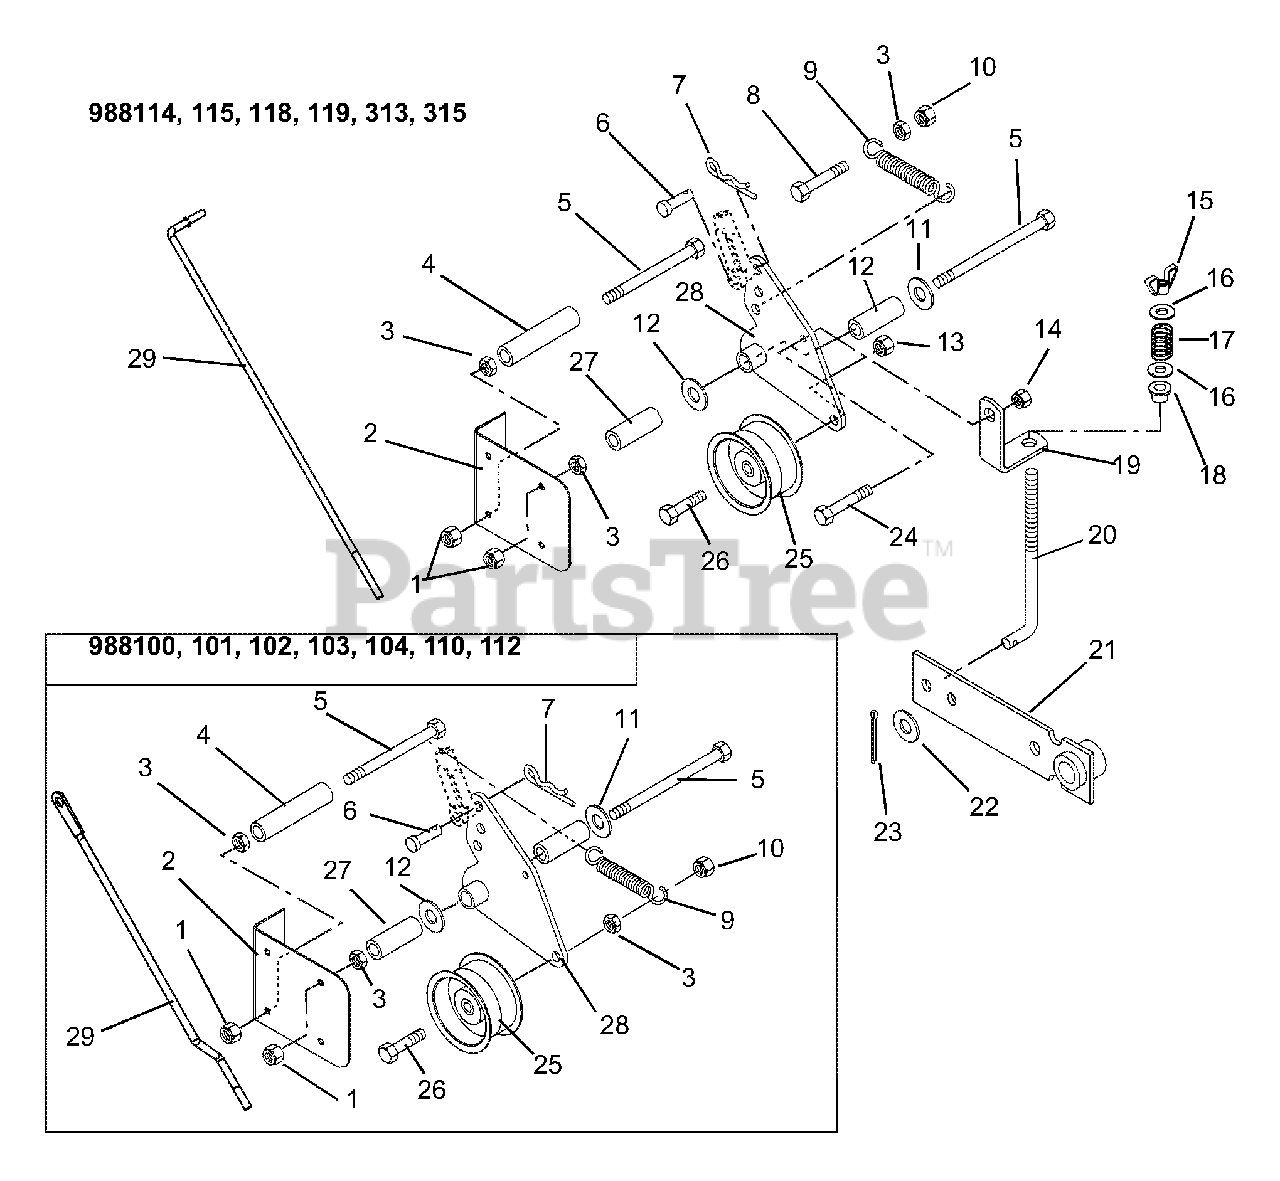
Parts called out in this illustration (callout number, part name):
1	Nut-Locking-Flange .375-16
2	Kit-Belt Cover with Decals
3	Nut-Hex .38-16
4	Bushing, Spacer, 3.25 x .38 I.D. x .63 O.D.
5	Bolt-Hex .38-16 x 4.50 Grade 5
6	Pin-Clevis .38 x 1.25
7	Pin-Hair Internal .08 x .18 x 1.18
8	Bolt-Hex .38-16 x 1.50 Grade 5
9	Spring-Tension .105 x 1.00 x 5.00
10	Nut-Locking-Nylon .38-16
11	Washer-Flat-Steel .406 x .812 x .065
12	Bushing, Steel .385 x .610 x 1.80
13	Nut-Locking-Jam-Center .38-16
14	Nut-Locking-Nylon .25-20
15	Nut-Nylock Wing .31-18
16	Washer-Flat-Steel .38 x .875 x .083
17	Spring-Compression .125 x .78 x 1.00
18	Bushing-Flange .32 x .62 x .312
19	Bracket, Brake Link
20	Rod, Brake
21	Weldment, Brake Arm
22	Washer-Flat-Steel .344 x .688 x .065
23	Pin-Cotter .09 x .75
24	Bolt-Hex .25-20 x .75 Grade 5
25	Sheave 3.25 x 1.25
26	Bolt-Hex .38-16 x 2.00 Grade 5
27	Bushing, Spacer
28	Weldment- Wheel Clutch Arm
29	Rod, Steering (988114, 115, 118, 119, 313, 315)
29	Rod, Steering Link (988100, 101, 102, 103, 104, 110, 112)
